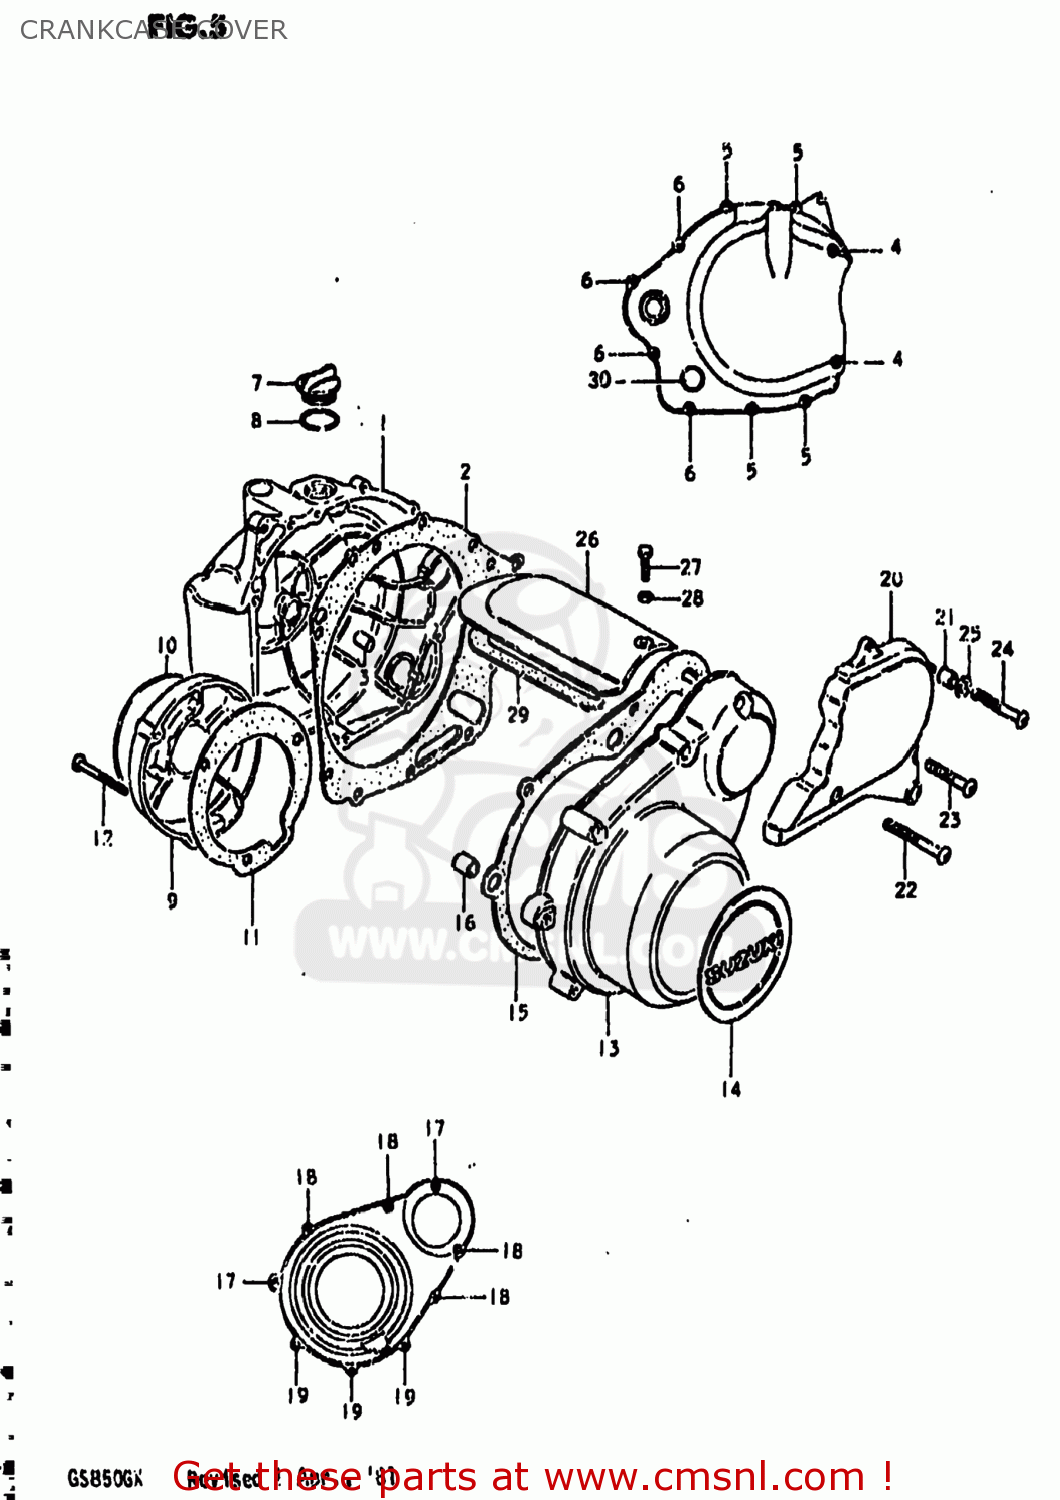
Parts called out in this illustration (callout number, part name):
1	COVER,CLUTCH
2	GASKET,CLUTCH COVER (MCA)
3	DOWEL PIN
4	SCREW 6X65
5	SCREW
6	SCREW
7	CAP
8	O RING(D:2.2,ID:32)
9	COVER,CONTACT BREAKER
10	EMBLEM
11	GASKET,CONTACT BREAKER COVER (NAS)
12	SCREW
13	COVER
14	EMBLEM
15	GASKET,MAGNETO COVER (MCA)
16	PIN
17	SCREW (6X45)
18	SCREW
19	SCREW (6X35)
20	COVER,SPROCKET
21	PIN
22	SCREW 6X30
23	SCREW
24	SCREW
25	WASHER
26	COVER,STARTER MOTOR
27	BOLT
28	WASHER
29	GASKET,STARTER MOTOR COVER (MCA)
30	LENS,OIL LEVEL CHECK
